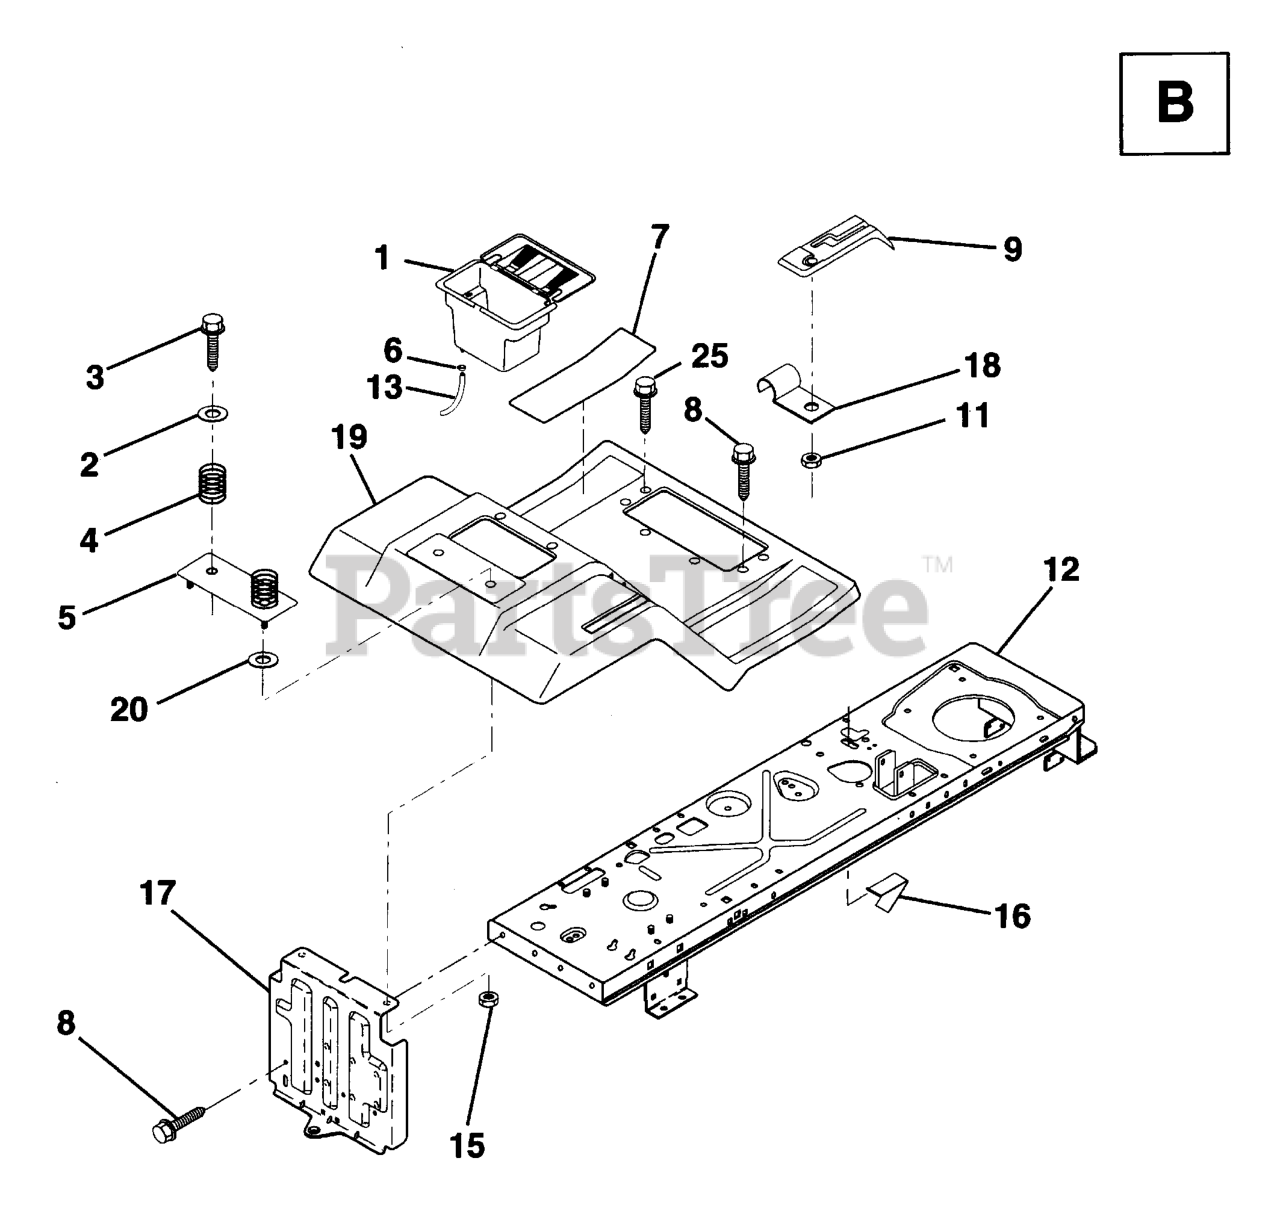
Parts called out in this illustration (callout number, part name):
1	CASE BATTERY
2	WASHER
3	SCREW
4	SPRING COMPRESSION
5	PLATE ASM BATTERY
6	HOSE CLAMP T
7	FOOTREST PAD
8	SCREW.THDROL.5/16-18X3/4.TTY
9	CONSOLE SHIFT CTL
11	NUT.PUSH.3/16
13	TUBE BATTERY DRAIN
15	LOCKNUT
16	SWITCH ACTUATOR
18	CLIP,INSULATOR
19	FENDER/FOOTREST
20	WASHER
25	SCREW
